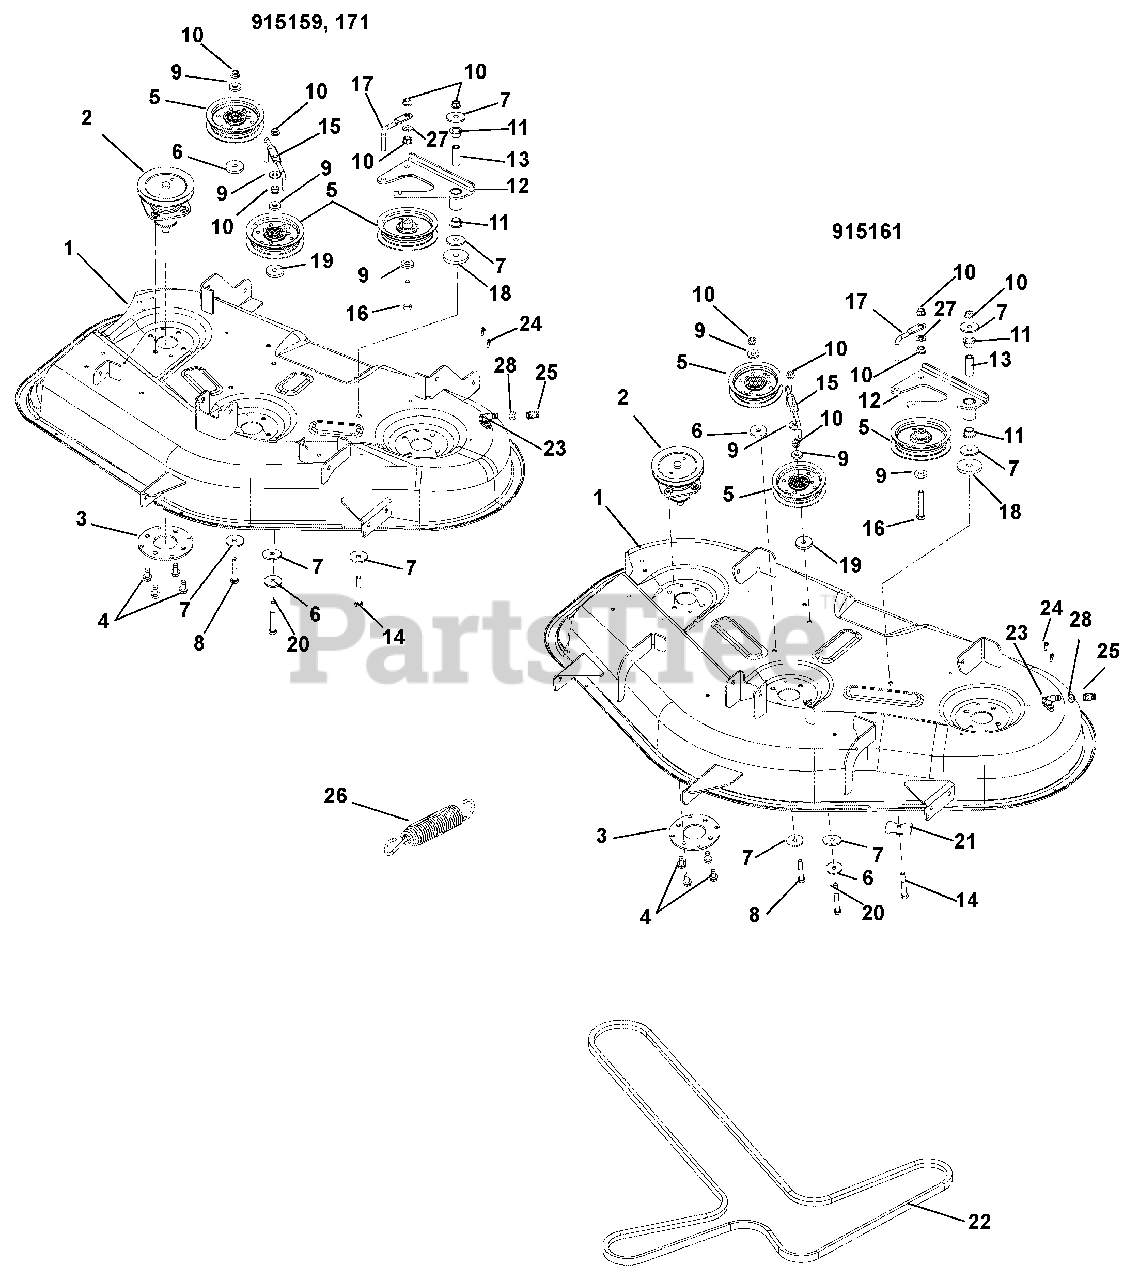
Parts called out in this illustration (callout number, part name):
1	KIT, 42" ARIENS DECK W/DECALS
1	KIT, 50" ARIENS DECK W/DECALS
2	KIT, DECK SPINDLE ASM (42)
2	KIT, DECK SPINDLE ASM (34/50)
3	PLATE-REINF, SPINDLE
4	@SCR-TAP .38-16X.75 HWH TR YWZ
5	ASM, IDLER 4"
6	WSHR,FLT STL.406X1.50X.245YWZC
7	WSHR-FL-STL .380X1.50X.125YWZC
8	@BLT-HEX .38-16X2.25 GR5 YWZC
9	WSHR-FL-STL .406X1.00X.188 YWZ
10	@NUT-LK-TOP-FLG .38-16 YWZC
11	BSHG-FLG, .625X.750X.500X1.00
12	IDLER ARM
13	SPACER, .375IDX.625ODX1.66 PM
14	@BLT-HEX .38-16X3.00 GR5 YWZC
15	WIREFORM, BELT FINGER
16	@BLT-HEX .38-16X2.25 GR5 YWZC
17	WIREFORM, BELT FINGER
18	WSHR-FL-STL .469X2.00X.25 YWZC
19	@WSHR-FL-STL.438X1.00X.083 YWZ
20	@BLT-HEX .38-16X2.75 GR5 YWZC
21	PLATE-DECK REINF.
22	V-BELT, 4L-WRAPPED
23	ASSY, WASHOUT PORT W/ O-RING
24	@SCR-TAP .25-20X.62 HWH TR YWZ
25	COUPLING, QUICK DISCONNECT
26	SG-TENS .135X.98X6.0 WLD 62
27	@WSHR-FL-STL.406X.812X.065 YWZ
28	O-RING .362X.103X.568
